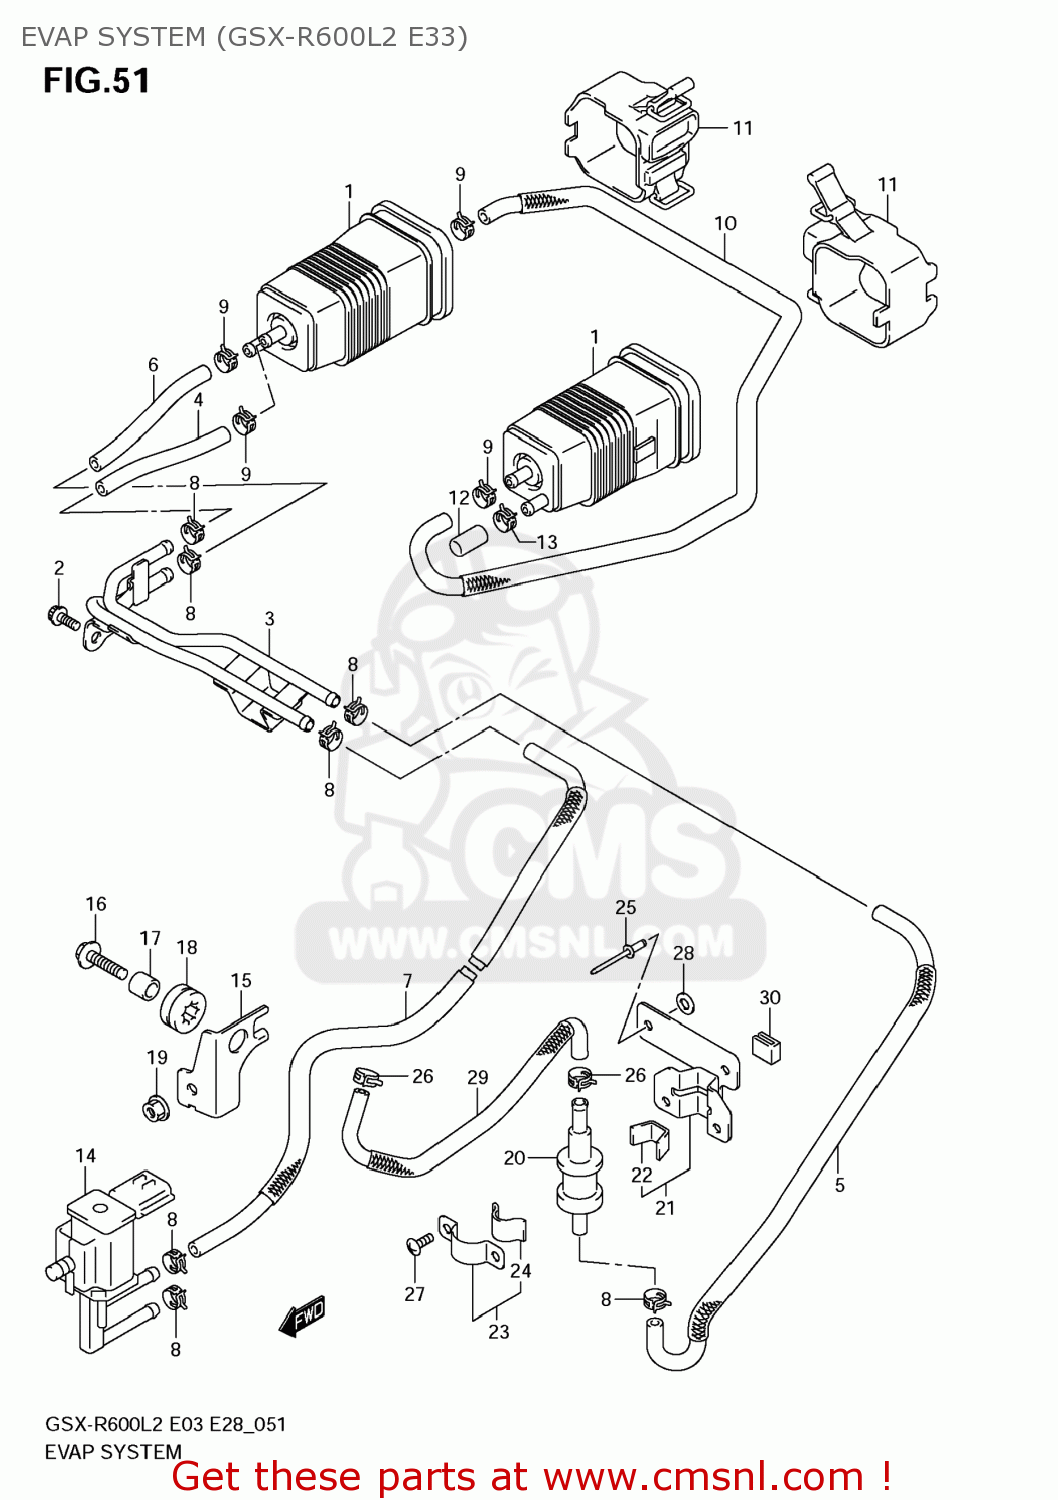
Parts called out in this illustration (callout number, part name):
1	CANISTER ASSY,CHARCOAL
2	BOLT
3	PIPE,EVAP
4	HOSE,SURGE NO.1
5	HOSE,SURGE NO.2
6	HOSE,PURGE NO.1
7	HOSE,PURGE NO.2
8	CLIP
9	CLIP
10	HOSE,CANISTER JOINT
11	CUSHION,CANISTER
12	CAP,OD:11.5
13	CLIP
14	VALVE ASSY,DUTY FOR PURGE
15	BRACKET,PURGE VALVE
16	BOLT(6X30)
17	SPACER(6.5X10X11.6)
18	CUSHION
19	NUT
20	VALVE,FUEL TANK BREATHER
21	PLATE,BREATHER VALVE
22	CUSHION
23	PLATE,FUEL TANK BREATHER NO.2
24	CUSHION
25	RIVET
26	CLIP
27	SCREW
28	WASHER
29	HOSE,TANK & BREATHER VALVE
30	CUSHION
